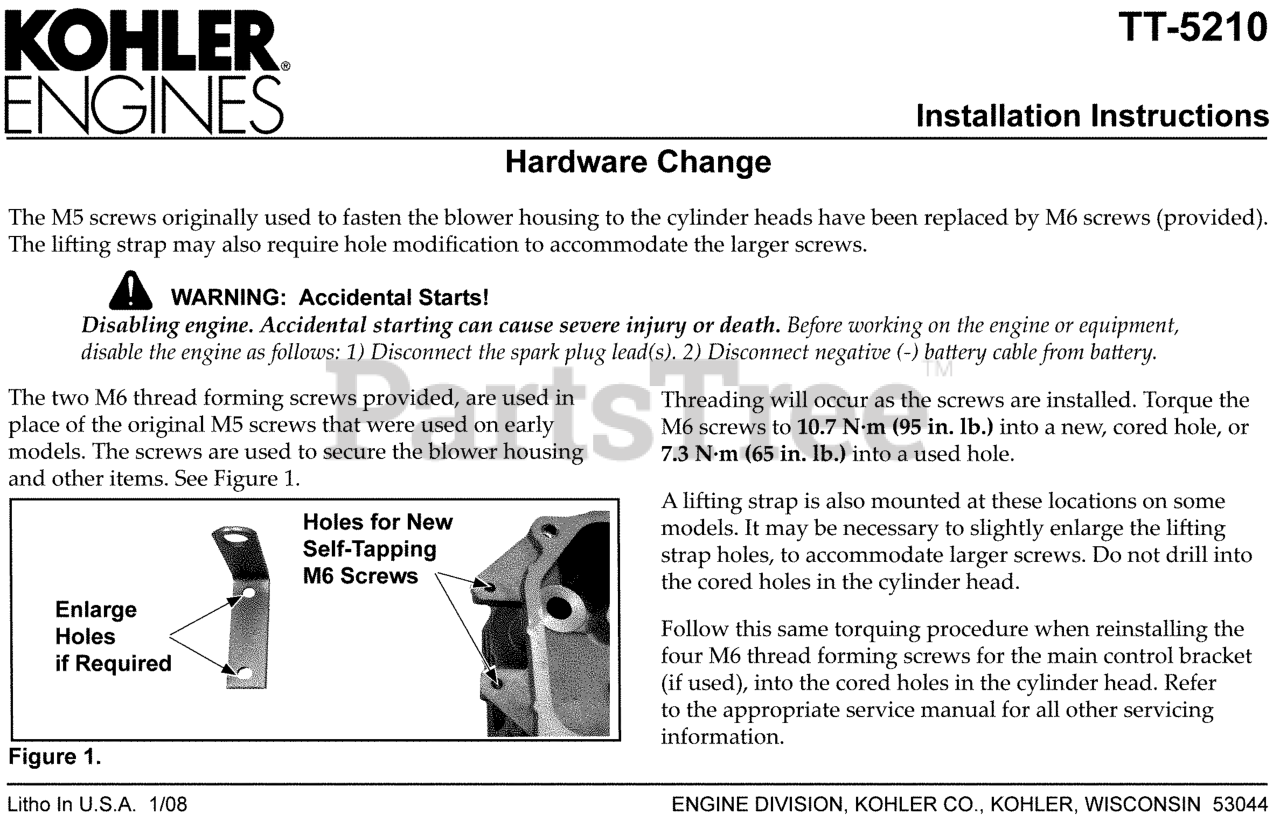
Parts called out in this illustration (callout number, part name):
1	KIT, BLOWER HOUSING ASSEMBLY USE 24 027 477-S
2	NUT, PLASTIC
3	SCREW, SKT SET #10-24X1/4"
4	NUT, PLASTIC (KM)-USE 25 100 37-S
5	SCREW, HVY FLG M5X.8X16
6	SCREW,FLG THD FRM M5X0.8X16-(#25086398S)
7	SCREW, FLG THD FRM M5X.8X20-(#25086399S)
8	PLATE, BACKING - #2 SIDE-USE 24 146 59-S
9	SCREW,FLG THD FRM M6X1.0X16-(#25086397S)
11	BAFFLE,VALLEY #2SIDE(KM)-USE 24 063 70-S
12	SCREW, FLG THD FRM M5X.8X10
14	BAFFLE, RIGHT BARREL-USE 24 063 85-S
15	PLATE, BACKING - DISCONTINUED
